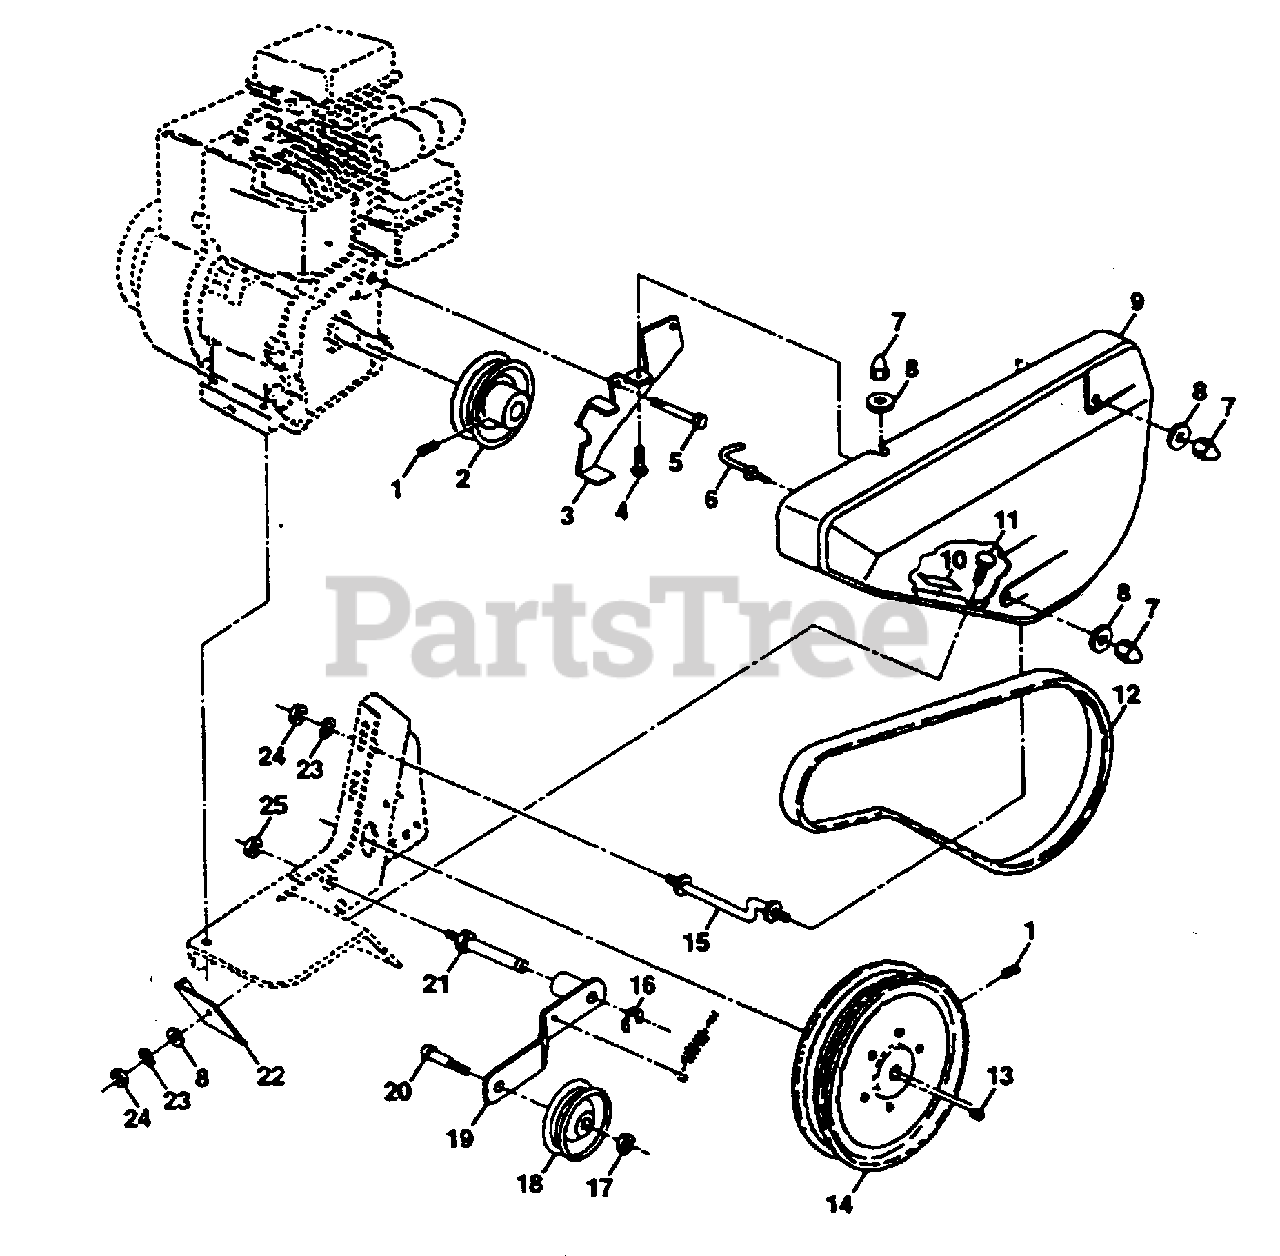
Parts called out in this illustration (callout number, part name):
1	Screw, Set, Forged Socket, Headless 5/16-18 x 3/8 (AYP part number)
2	Pulley, Engine
3	Bracket Assembly, Guard, Belt (AYP part number)
4	Bolt, Carriage 1/4-20 x 1/2 (AYP part number)
5	Bolt, Hex 1/2-20 x 3/4 (AYP part number)
6	Keeper, Belt, Transmission Pulley (AYP part number)
7	Nut, Cap 1/4-20 (AYP part number)
8	Washer 9/32 x 5/8 x 16 Ga. (AYP part number)
9	Guard, Belt (AYP part number)
10	Pad, Idler (AYP part number)
11	Bolt, Carriage 1/4-20 x 3/4 (AYP part number)
12	V-Belt (AYP part number)
13	Key, Square (AYP part number)
14	Pulley, Transmission (AYP part number)
15	Bolt, Belt Guard
16	Ring, Klip (AYP part number)
17	Nut, Hex, Jam 3/8-16 (AYP part number)
18	Pulley, Idler (AYP part number)
19	Idler Arm Assembly (AYP part number)
20	Bolt, Hex 3/8-16 x 1-1/4 (AYP part number)
21	Shaft, Idler Arm (AYP part number)
22	Shield, Dirt (AYP part number)
23	Washer, Lock 1/4 (AYP part number)
24	Nut, Hex 1/4-20 (AYP part number)
25	Nut, Hex, Jam 5/16-18 (AYP part number)
